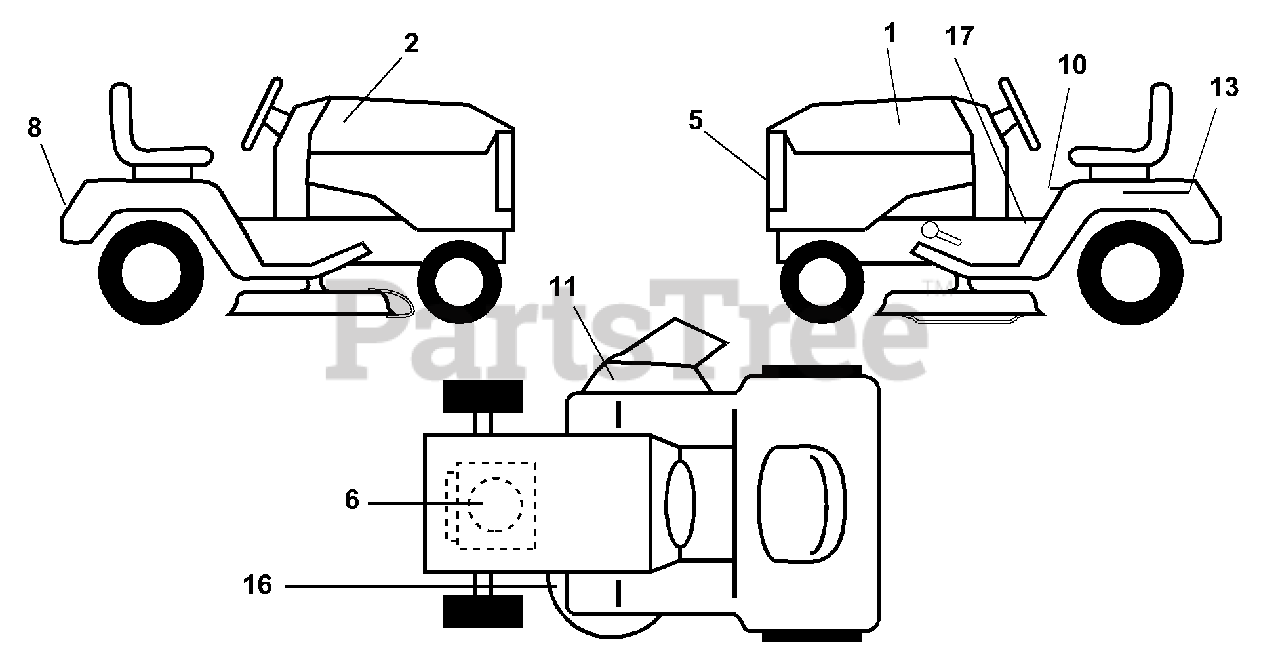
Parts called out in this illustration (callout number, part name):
1	Decal, Hood, L. H., Husqv.
2	Decal, Hood, R. H., Husqv.
5	Decal, Logo, Grill
6	Decal, Engine
8	Decal, Logo, Fender
10	Decal Caution Fender
11	Decal, Warning, Cut Finger, (Multi-Lang)
13	Decal, Caution, Battery
16	Decal, V-Belt Sch.
17	Decal, Inst. Oper.
